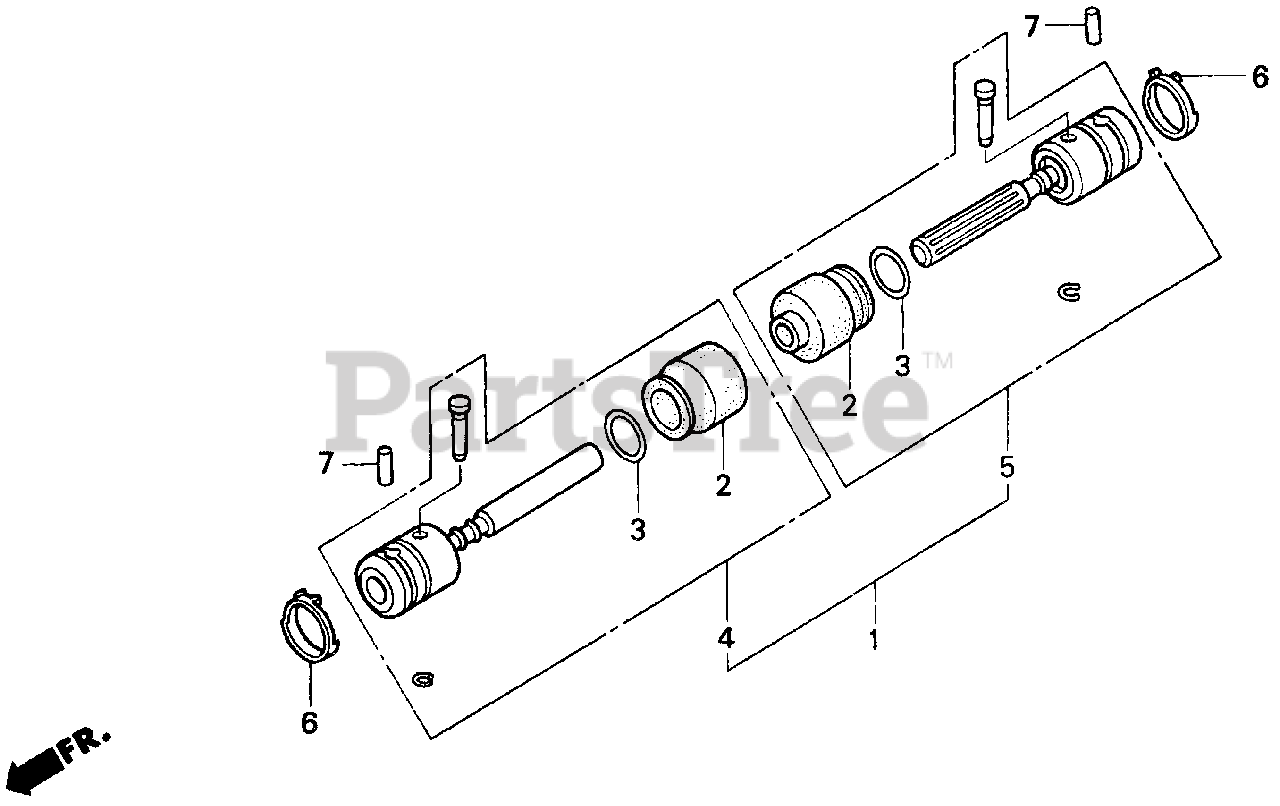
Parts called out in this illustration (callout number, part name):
1	JOINT ASSY.
2	BOOT, JOINT
3	RING, SEAL
4	JOINT SUB-ASSY. (A)
5	JOINT SUB-ASSY. (B)
6	CLIP, CLUTCH SHAFT
7	ROLLER (4X17.8)
